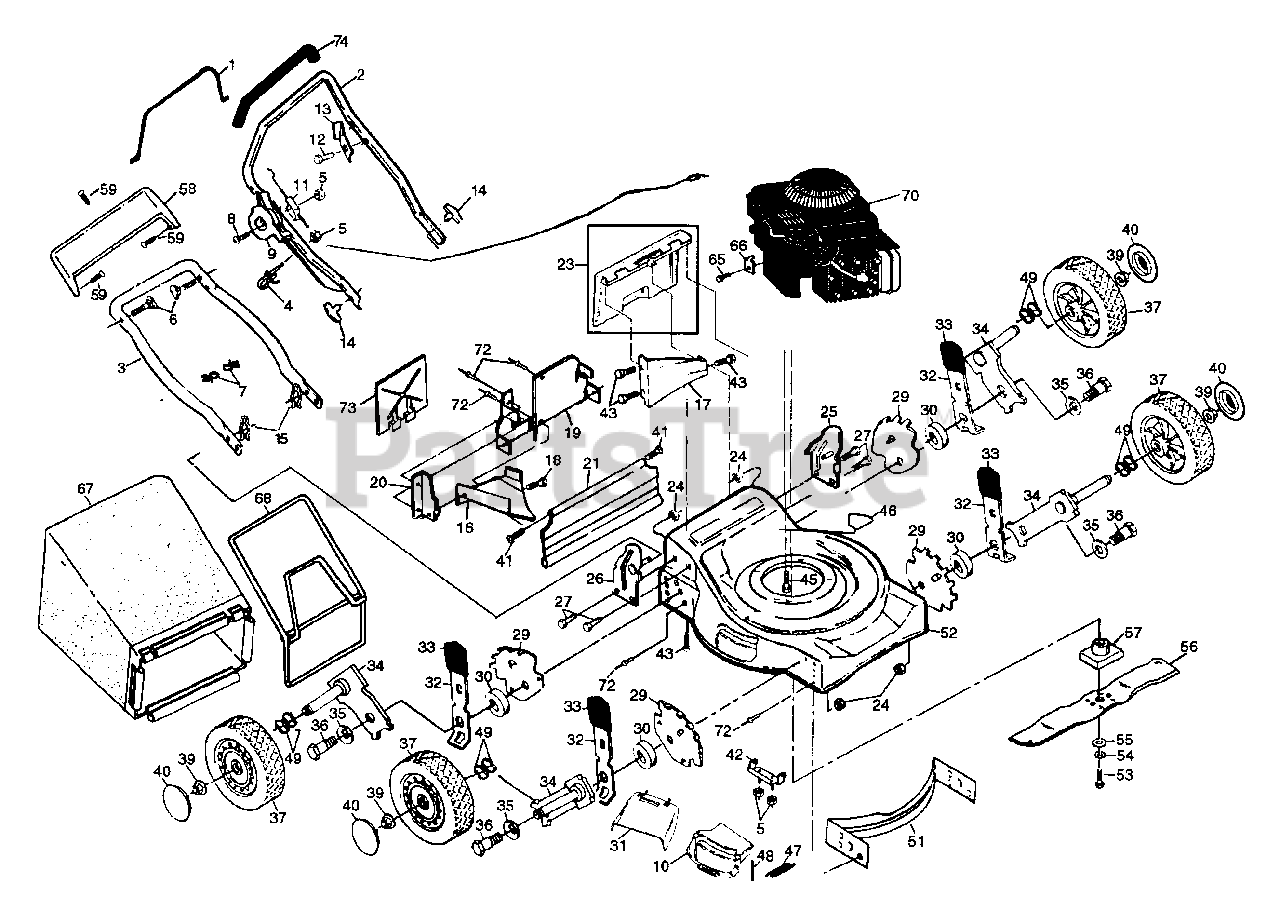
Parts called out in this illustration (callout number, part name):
1	Control Bar
2	Upper Handle
3	Lower Handle
4	Rope Guide
5	Locknut 1/4-20
6	Handle Bolt
7	Cable Clips
8	Hex Washer Head Screw 1/4-20 x 2-1/8
9	Throttle Control
10	Combi-cut Door
11	Engine Zone Control Cable
12	Hex Washer Head Screw #10-24 x 1/2
13	Up-Stop Bracket
14	Handle Knob
15	Hairpin Cotter
16	Discharge Baffle
17	Rear Baffle
18	Hex Head Screw #10-24 x 1/2
19	Back Plate
20	Side Baffle
21	Rear Skirt
23	Rear Door Assembly Kit
24	Locknut 3/8-16
25	Handle Bracket Assembly (Left)
26	Handle Bracket Assembly (Right)
27	Screw 5/16-18 x 3/4
29	Wheel Adjusting Bracket
30	Spacer
31	Clip-on Discharge Guard
32	Selector Spring
33	Selector Knob
34	Axle Arm Assembly
35	Belleville Washer
36	Shoulder Bolt 3/8-16
37	Wheel Assembly
39	Flanged Locknut
41	Hinge Screw
42	Hinge Bracket
43	Hex Tapping Screw 1/4-20 x 1/2
45	Hex Head Thread Rolling Screw 3/8-16 x 1
46	Danger Decal
47	Hinge Spring
49	Wave Washer
51	Front Baffle
52	Housing Assembly
53	Hex Head Screw 3/8-24 x 1-3/8 Grd. 8
54	Helical Lockwasher
55	Hardened Washer
57	Blade Adapter
58	Trim Plate
59	Push-in Fastener
65	Screw #10 x 5/8
66	Cable Clamp
67	Grass Bag
68	Catcher Frame
70	Engine - Briggs & Stratton
73	Mulcher Plate
74	Handle Grip
